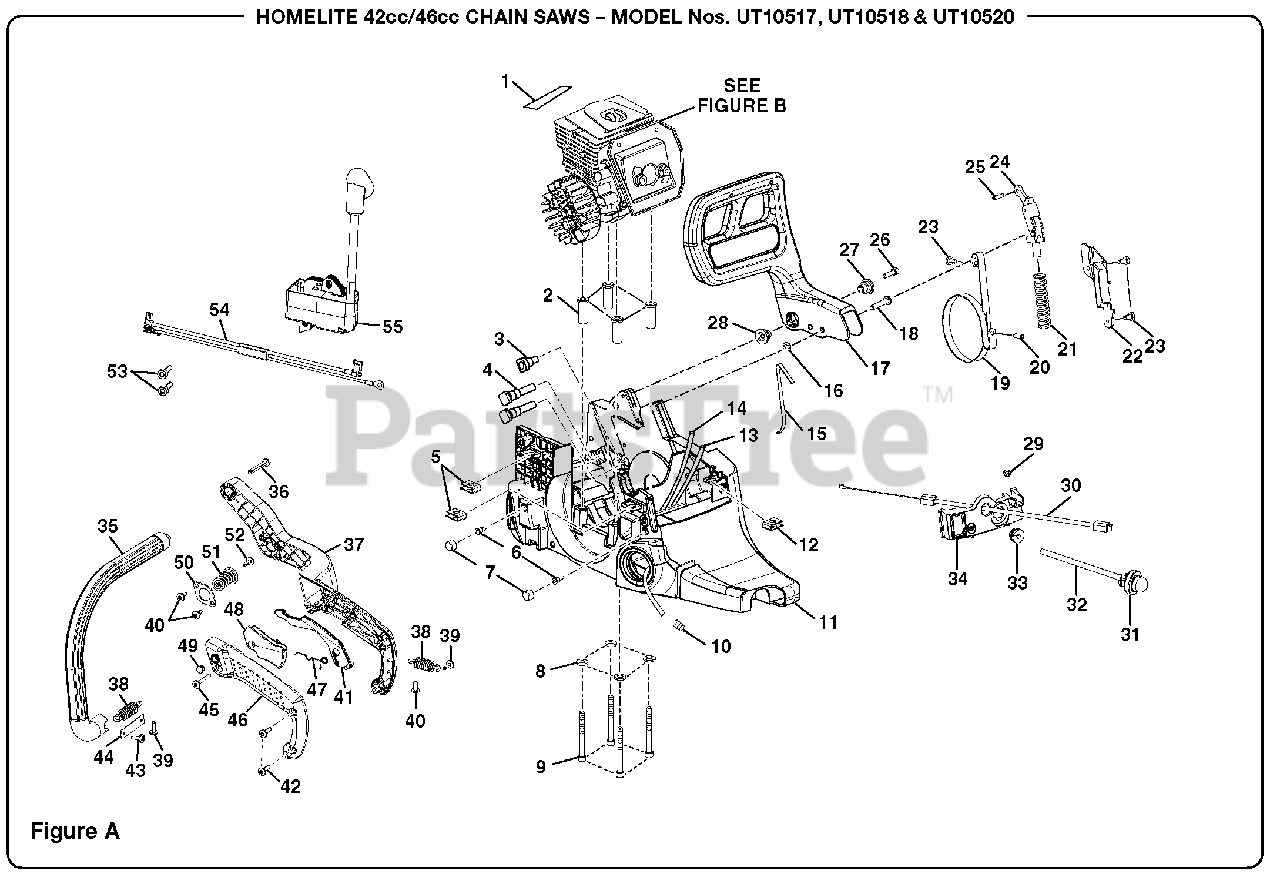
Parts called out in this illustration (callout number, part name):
1	Fuel Pump
2	Rubber Tubing
3	Split Grommet
4	Control Panel, Black
5	Control Panel, Gray
6	Front Handle, Black
7	Front Handle, Gray
8	Screw (12-14 x 1 1/2 in.)
9	Rear Handle, Black
10	Rear Handle, Gray
11	Extension Spring
12	Screw (10-14 x 1/2 in.)
13	Lockout Throttle, Yellow
14	Lockout Throttle, Black
15	Screw (10-14 x 3/4 in.)
16	Screw (10-14 Thread Twin Helix)
17	Spring Retainer
18	Handle Cover, Black
19	Handle Cover, Gray
20	Torsion Ring
21	Trigger, Yellow
22	Trigger, Black
23	Plug, Black
24	Plug, Gray
25	Isolator Plate
26	Isolator Spring
27	Screw (10-24 x 5/8 in.)
28	Screw (8-32 x 5/8 in.)
29	Ignition Switch Harness
30	Ignition Kit
31	Fuel Pump
32	Rubber Tubing
33	Split Grommet
34	Control Panel, Black
35	Front Handle, Black
36	Screw (12-14 x 1 1/2 in.)
37	Rear Handle, Black
38	Extension Spring
39	Screw (10-14 x 5/8 in.)
40	Screw (10-14 x 1/2 in.)
41	Lockout Throttle, Yellow
42	Screw (10-14 x 3/4 in.)
43	Screw (10-14 Thread Twin Helix)
44	Spring Retainer
45	Screw (10-14 x 1 3/8 in.)
46	Handle Cover, Black
47	Torsion Ring
48	Trigger, Yellow
49	Plug, Black
50	Isolator Plate
51	Isolator Spring
52	Screw (10-24 x 5/8 in.)
53	Screw (8-32 x 5/8 in.)
54	Ignition Switch Harness
55	Ignition Kit
